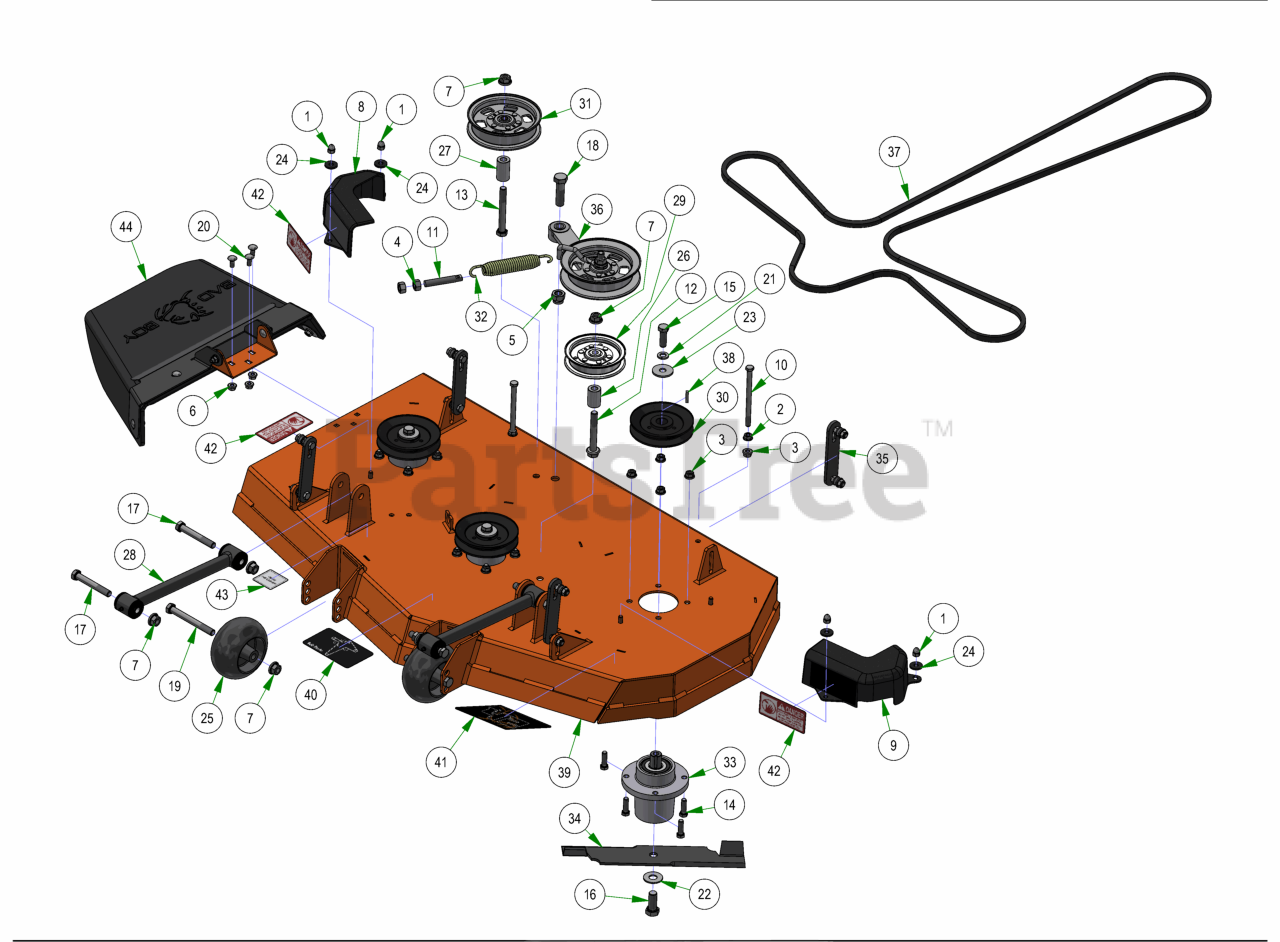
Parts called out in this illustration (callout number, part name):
1	5/16-18 ACORN NUT HIGH-CROWN ZC
2	3/8-16 HEX SERRATED FLANGE NUT HARD/ZINC
3	3/8-16 NYLON INSERT FLANGE LOCKNUT (GR.F) ZINC
4	1/2-13 HEX NUT ZINC
5	5/8-11 NYLON INSERT LOCKNUT ZINC
6	5/16-18 NYLON INSERT FLANGE LOCKNUT ZINC
7	1/2-13 NYLON INSERT FLANGE LOCKNUT ZINC
8	Pulley Cover Chute Side
9	Pulley Cover Non-Chute Side
10	3/8-16 X 5-1/4 HEX CAP SCREW (GR.5) ZINC
11	All Thread
12	1/2-13 X 3-1/2 HEX FLANGE BOLT (GR.8) ZINC
13	1/2-13 X 4 HEX CAP SCREW (GR.8) ZINC YELLOW
14	3/8-16 X 1-1/4 HEX CAP SCREW (GR.5) ZINC
15	1/2-20 X 1-1/2 HEX CAP SCREW (GR.5) ZINC
16	5/8-18 X 1-1/2 HEX CAP SCREW (GR.8) ZINC YELLOW
17	1/2-13 X 3-1/2 HEX CAP SCREW (GR.5) ZINC
18	5/8-11 X 2-1/4 HEX CAP SCREW (GR.5) ZINC
19	1/2-13 X 4-1/2 HEX CAP SCREW (GR.5) ZINC
20	5/16-18 x 3/4 Carriage Bolt
21	1/2 SPLIT LOCKWASHER (GR.8) ZINC/YELLOW
22	5/8 USS FLAT WASHER (1-3/4" OD) GR.8 ZINC YELLOW
23	1/2 BELLEVILLE WASHER (1-5/8 OD X .140 THK) ZINC
24	.360 ID X .983 OD X .120 THICK FLAT WASHER NYLON BLACK
25	2019 Deck Wheel
26	.502 ID X .750 OD X 1.500 Long Spacer
27	1 3/4" Pulley Spacer
28	Hybrid Turnbuckle/Deck Locator
29	4 3/4" Idler Pulley
30	42" MZ Spindle Pulley
31	5-3/4 Idler Pulley
32	Deck Idler Spring
33	Spindle Assembly-MZ
34	42" High Lift Fusion Blade-MZ
35	Deck Hanger Assembly
36	Maverick HD & Down Deck Idler Assembly
37	2023 42" Deck Belt
38	3/16 X 1 SQ MACHINERY KEY 1018 STL ZINC
39	2025 42" x 4" Deck
40	2017 MZ Magnum 48"/42" Deck Route Decal
41	42" Grip Deck Decal
42	Danger Decal-Spindle/Discharge
43	Deck Impact Patent Decal 9591803
44	MZ Discharge Chute Assembly
